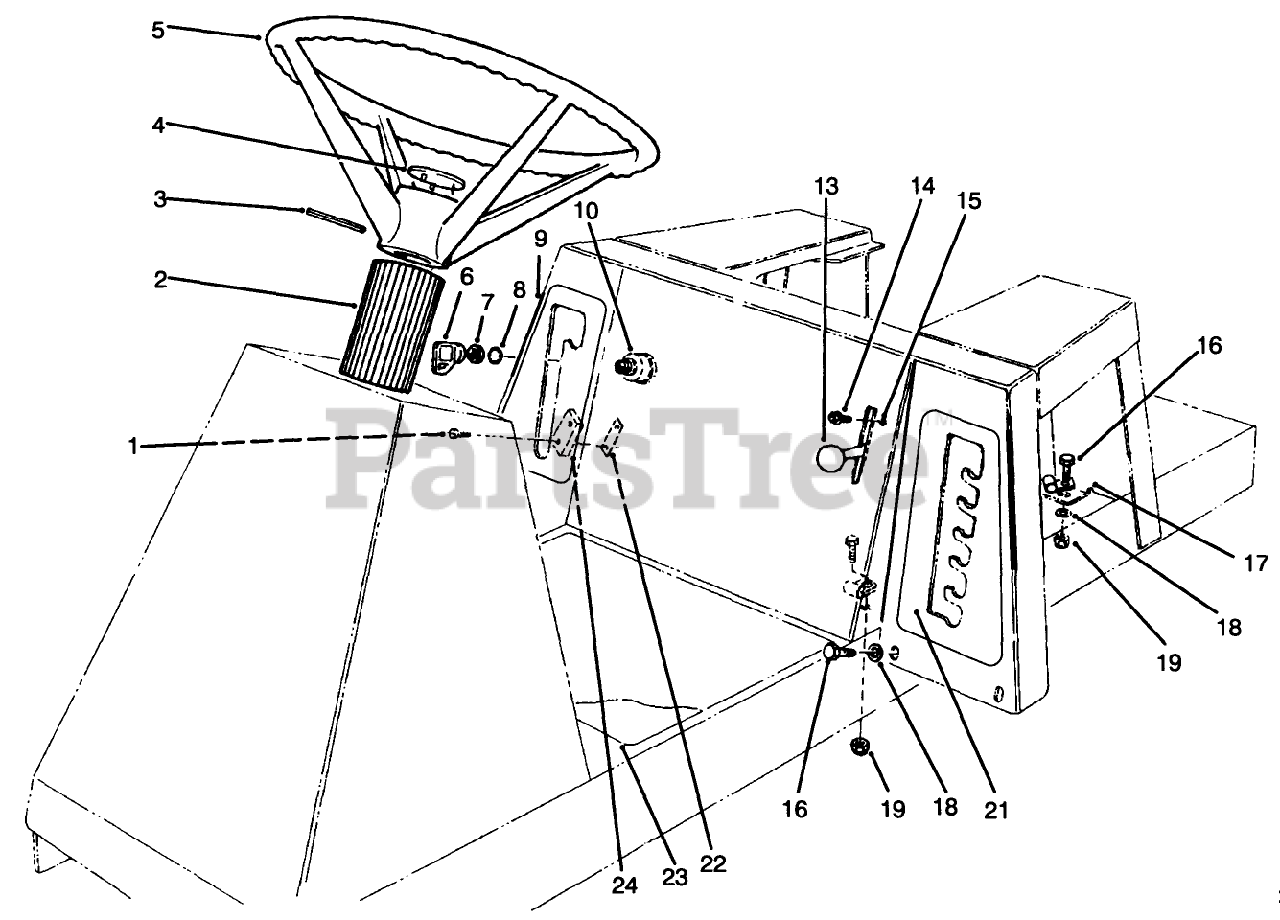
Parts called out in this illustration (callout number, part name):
2	COVER-STEERING SHAFT
3	PIN-ROLL
4	INSERT - STEERING WHEEL, WH EMBLEM
5	STEERING WHEEL ASM
6	KEY-IGNITION
7	NUT-HH
8	WASHER-LOCK
9	DECAL - DECK ENGAGE
10	SWITCH-STARTER
13	KNOB-CONTROL
14	SCREW-HWHTF
16	SCREW-HH
17	CLAMP
18	WASHER-PLAIN
19	NUT-LOCK, NI
21	DECAL - HOC
22	NUT-SPEED
24	SWITCH-MICRO
